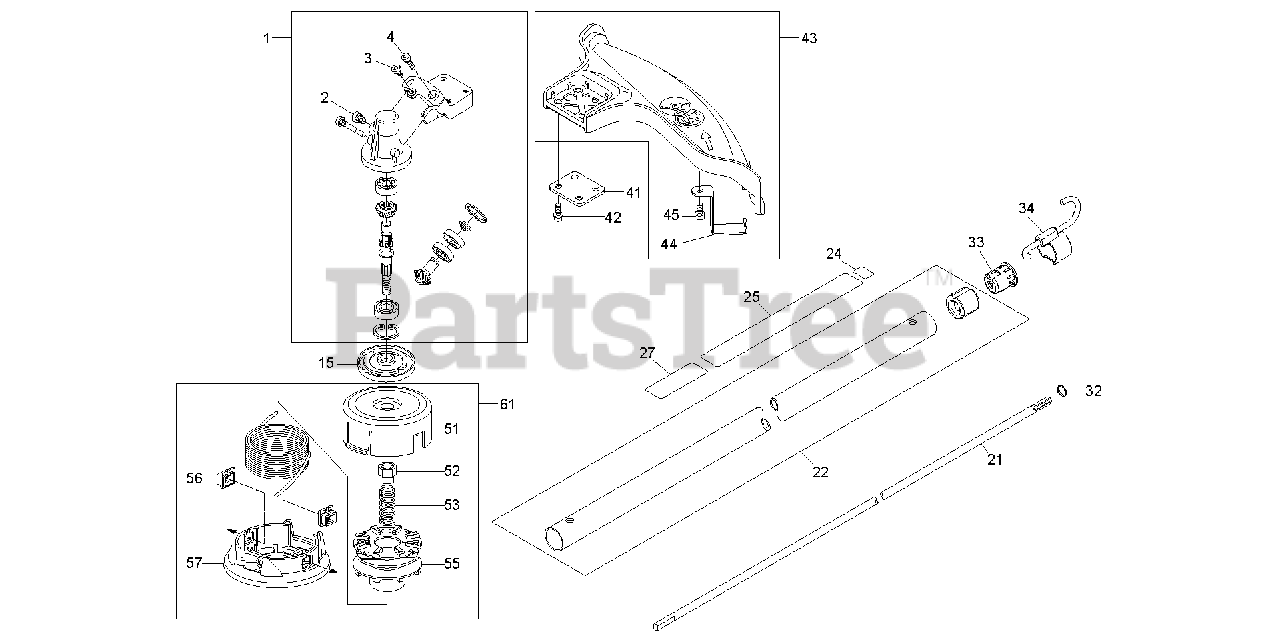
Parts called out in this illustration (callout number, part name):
1	CASE ASSY., GEAR
2	BOLT, TORX (6X8)
3	BOLT, TORX (5X10)
4	BOLT, TORX (5X20)
15	HOLDER A, BLADE
21	SHAFT, DRIVE
22	PIPE
24	MARK, ARROW
25	MARK, CAUTION
27	MARK, EMBLEM (SSST)
41	PLATE, DEFLECTOR
42	BOLT-WASHER, TORX (5X22)
43	DEFLECTOR ASSY., GRASS
44	PLATE, NYLON CUTTING
45	BOLT, TORX (5X10)
52	NUT (10X1.25L)
55	HOLDER, LINE
61	CUTTER ASSY., NYLON (Z5)
